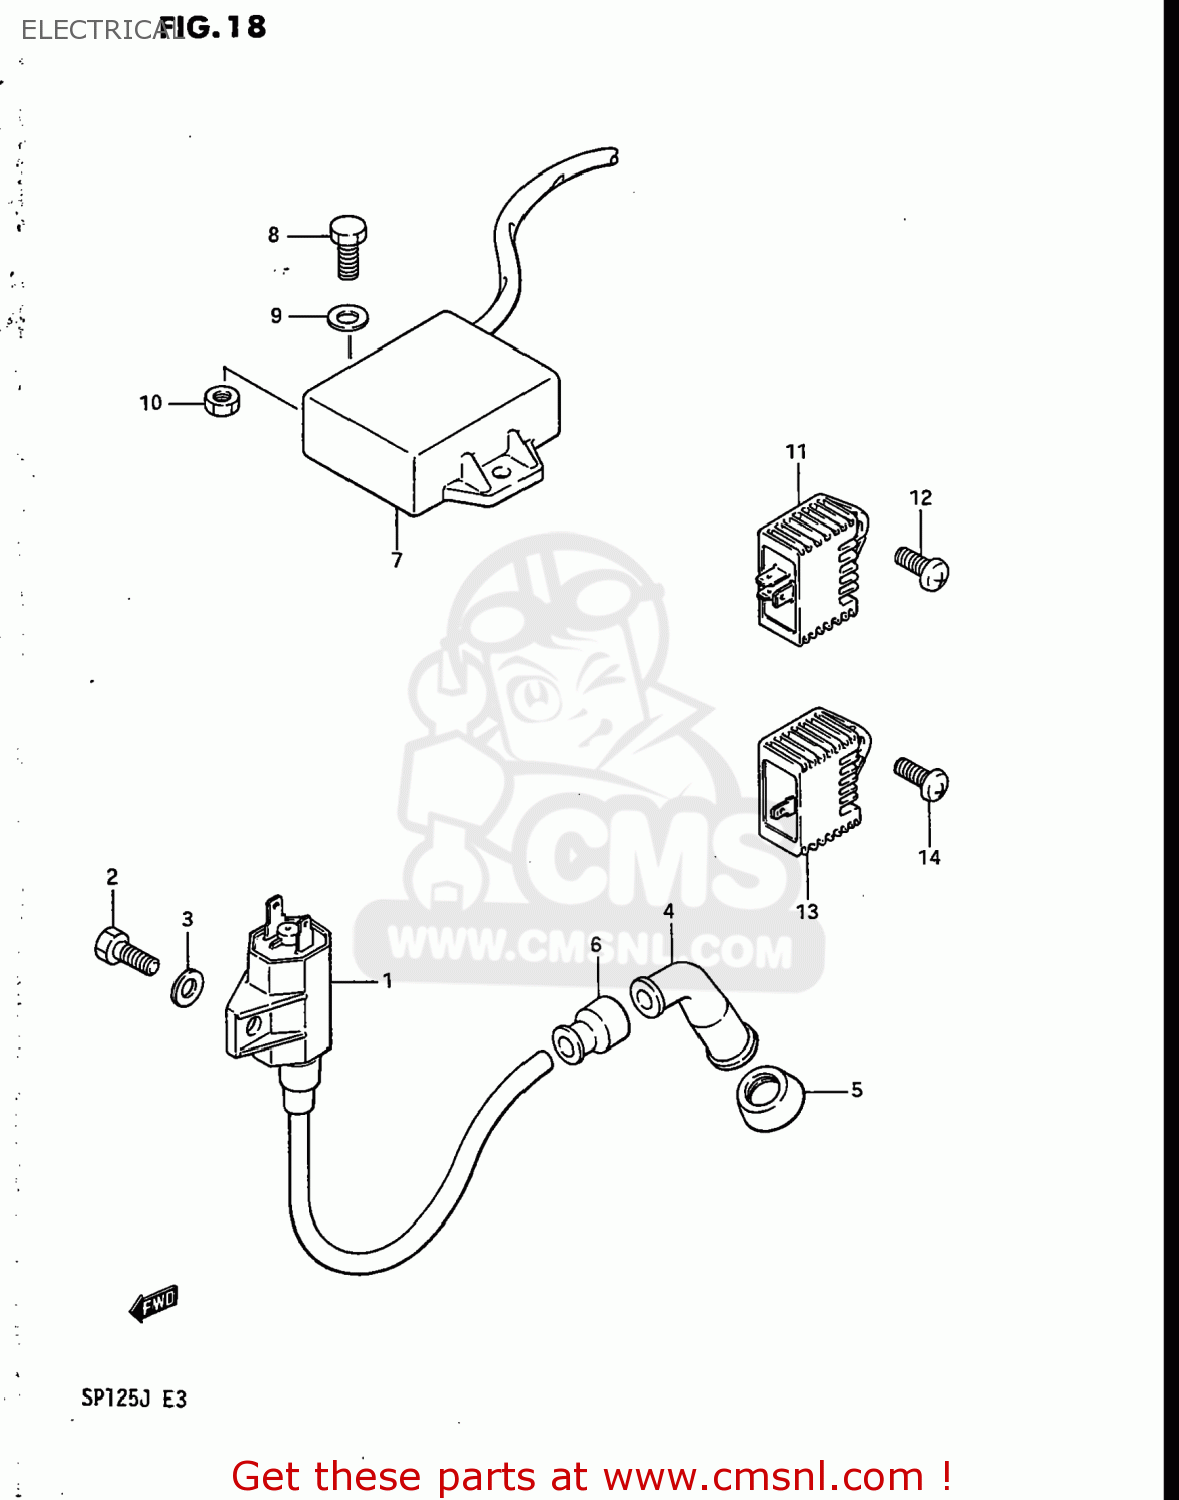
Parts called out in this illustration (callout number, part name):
1	COIL ASSEMBLY,IGNITION
2	BOLT
3	WASHER, LOWER
4	CAP,SPARK PLUG
5	SEAL,SPARK PLUG CAP
6	SEAL,SPARK PLU
7	CDI UNIT
8	BOLT
9	WASHER, LOWER
10	NUT
11	RECTIFIER ASSY,REGULATOR
12	SCREW
13	REGULATOR ASSY,VOLTAGE
14	SCREW
